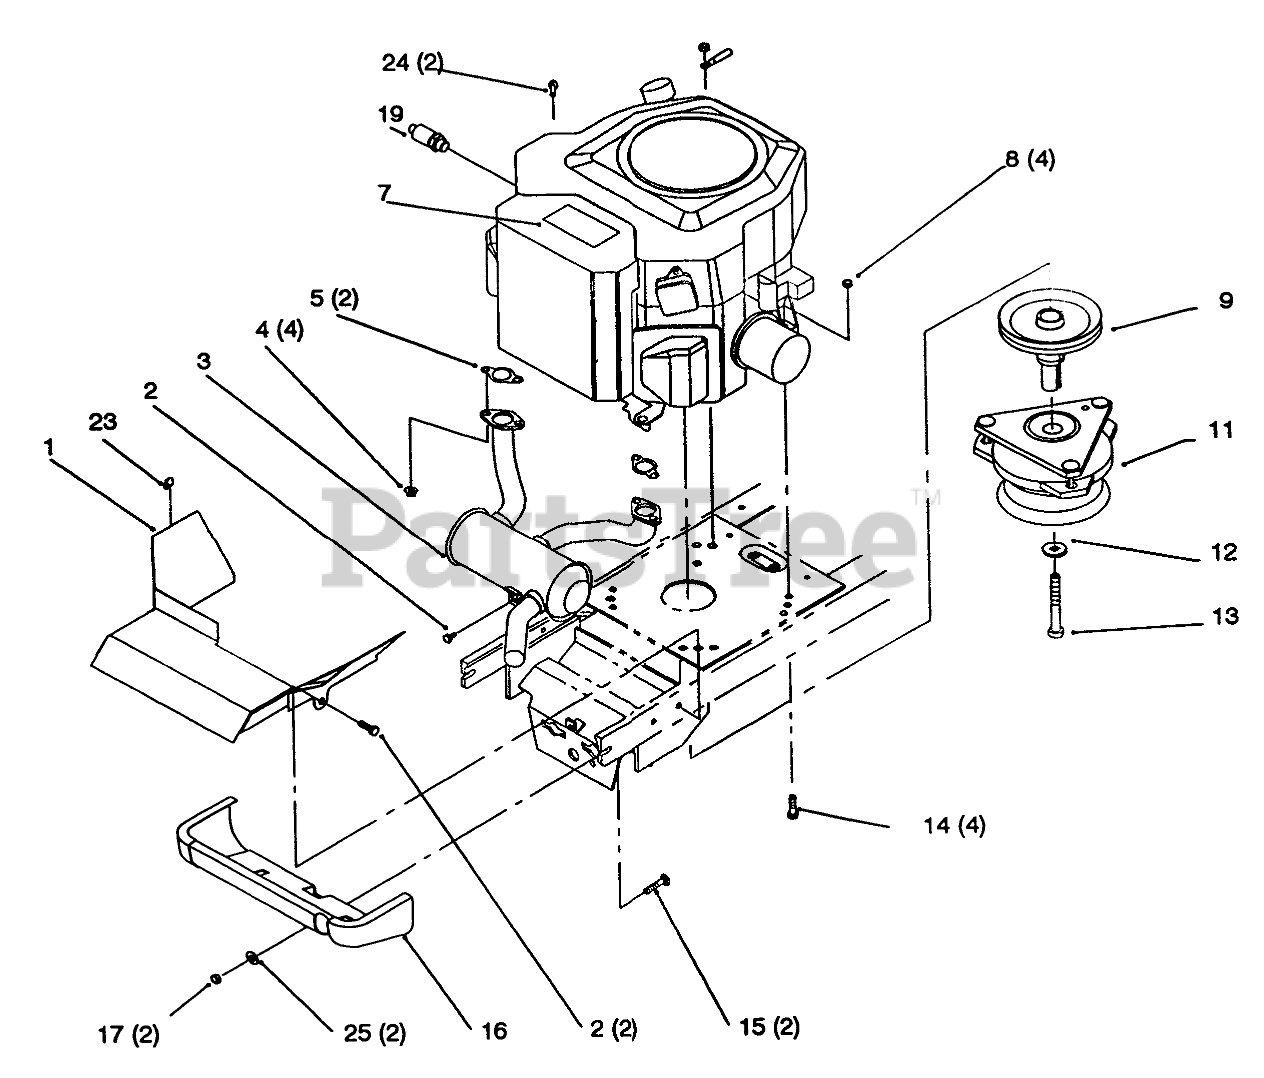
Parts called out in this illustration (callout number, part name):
1	Baffle-Muffler (Only On: 72103, 72083)
2	Screw-HWHTF (Only On: 72103, 72083)
3	Muffler (Only On: 72103, 72083)
4	Nut-HHF (Only On: 72103,72083)
5	Gasket-Exhaust (Only On: 72103, 72083)
7	Decal-Toro Power Plus 16 (Only On: 72083, 72103)
8	Nut-Hex Lock (Only On: 72103, 72083)
9	Pulley (Only On: 72083, 72103)
11	Clutch-PTO (Only On: 72103, 72083)
12	Washer-PTO (Only On: 72103, 72083)
13	Screw HH (Only On: 72103, 72083)
14	Screw-HH (Only On: 72103, 72083)
15	Bolt-CARR (Only On: 72103,72083)
16	Shield-Muffler (Only On: 72103, 72083)
17	Nut-Hex Lock (Only On: 72103, 72083)
19	Valve-Oil Drain (Only On: 72103, 72083)
23	Clip-Wire Retainer (Only On: 72103,72083)
24	Screw-PPH (Only On: 72103, 72083)
25	Washer-Flat (Only On: 72103, 72083)
